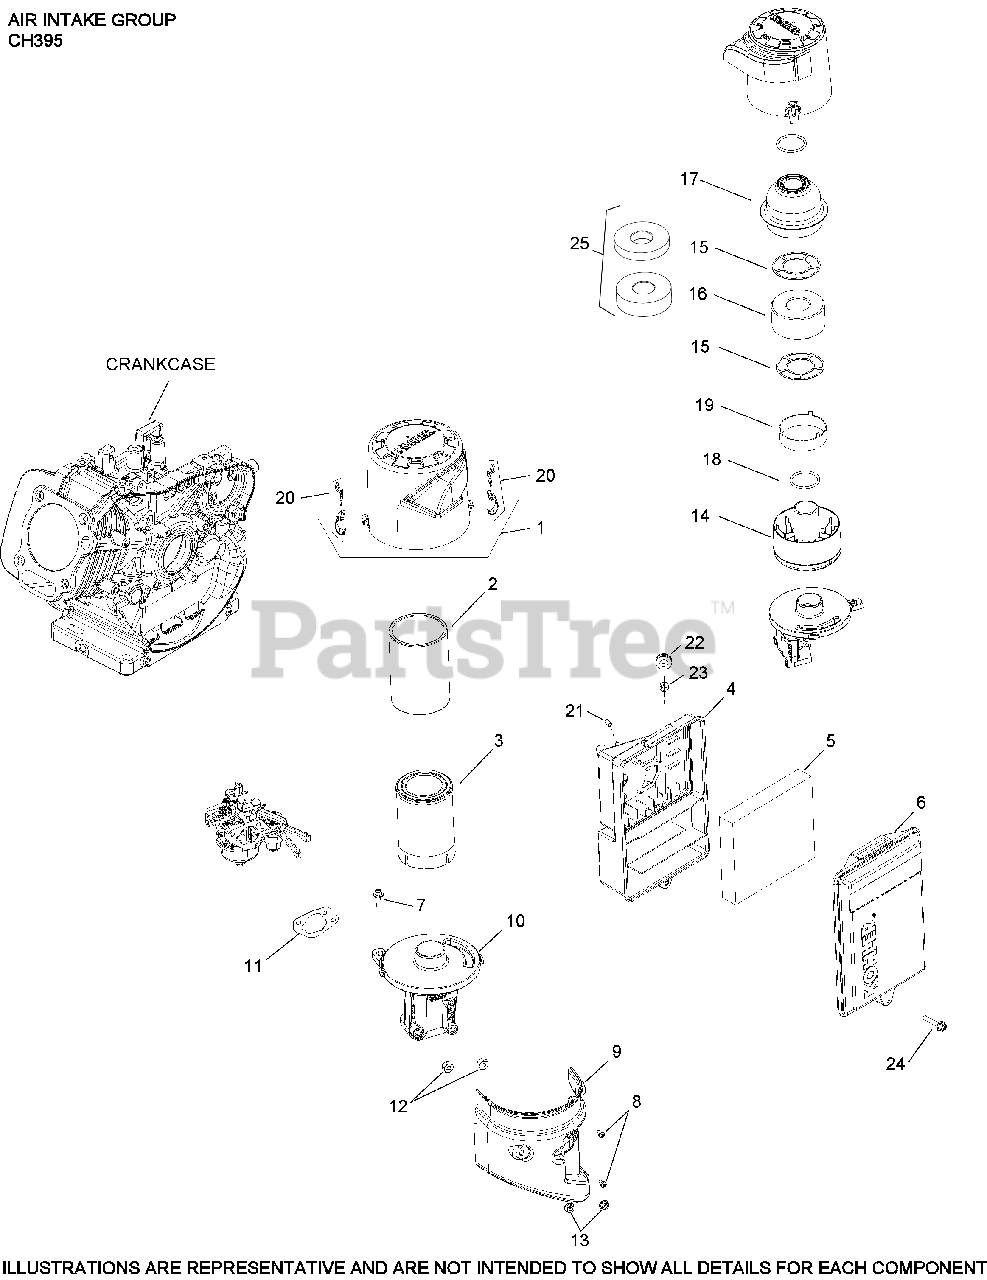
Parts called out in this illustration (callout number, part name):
4	BASE ASSEMBLY, AIR CLEANER
5	ELEMENT, AIR FILTER
6	COVER, AIR CLEANER
11	GASKET, AIR CLEANER
13	NUT, HEX FLANGE LOCK (M6)
21	CAP, MASKING (CKY)
22	ISOLATOR, VIBRATION
24	SCREW, HEX FLANGE SLOTTED (M6) (CKY)
